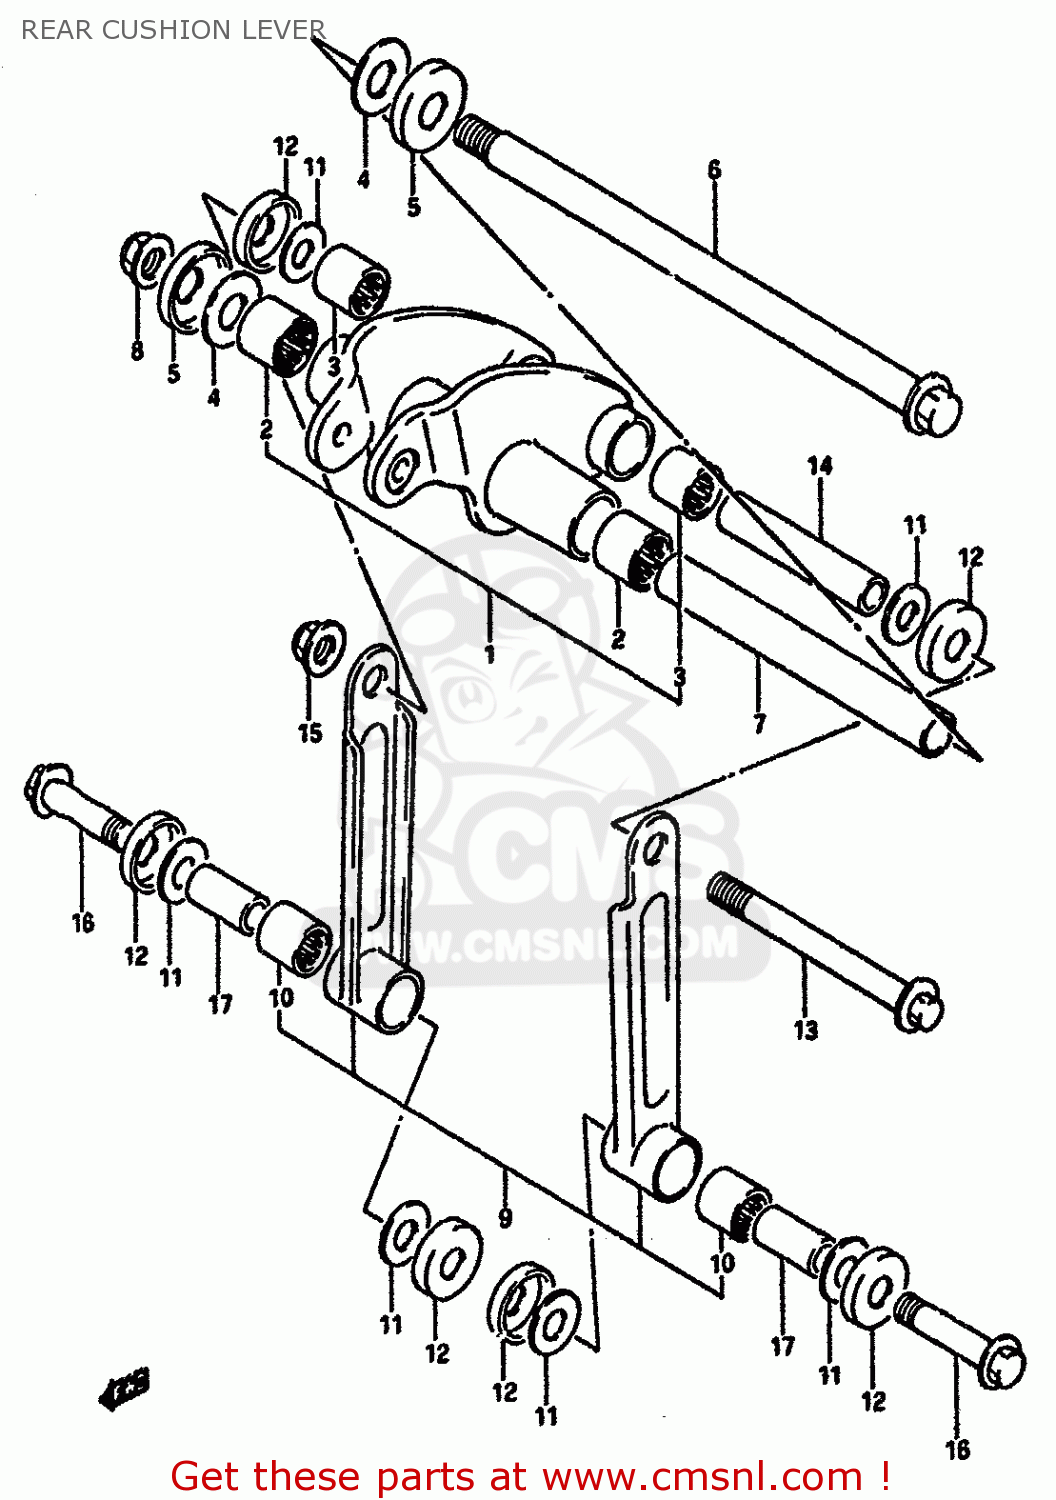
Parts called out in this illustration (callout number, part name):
1	LEVER SET,REAR CUSHION
2	BEARING(20X27X25)
3	ROLLER BEARING (17X24X25)
4	WASHER
5	SEAL,REAR CUSHION LEVER
6	SHAFT,REAR CUSHION LEVER
7	SPACER,RR CUSHION LEVER
8	NUT 12MM
9	ROD SET,REAR CUSHION
10	ROLLER BEARING (17X24X25)
11	WASHER
12	COVER,RR SWGARM DUST SEAL
13	BOLT,REAR CUSHION ROD
14	SPACER,RR CUSHION ROD UPR
15	NUT 12MM
16	RING,BEARING STOPPER
17	SPACER,RR CUSHION ROD LWR
